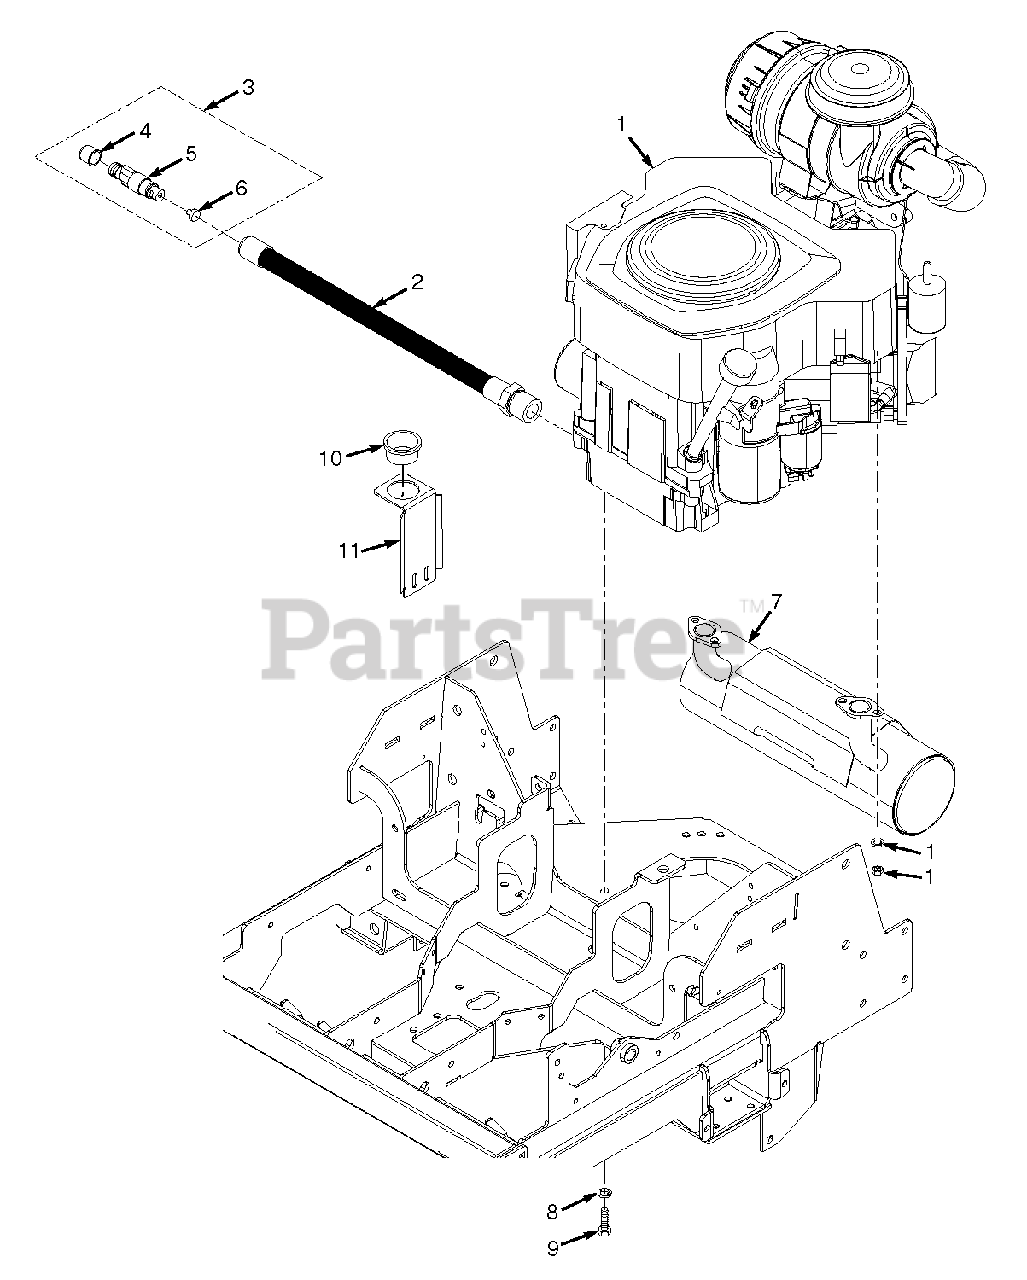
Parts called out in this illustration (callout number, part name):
1	Engine, Kawasaki FX691V
1	Engine, Kohler CV730
1	Engine, Kawasaki FX730V
1	Engine, Kohler CV740
1	Engine, Briggs & Stratton 44L977
2	Hose Assembly, Engine Oil Drain - Kawasaki FS/FX
2	Hose, Oil Drain - Briggs & Stratton ELS
2	Hose, Oil Drain - Kohler CV
3	Valve Assembly, Oil Drain
5	O-Ring
7	Muffler, Kawasaki FS/FX
7	Muffler, Briggs & Stratton
7	Muffler, Kohler CV
8	Lockwasher, 3/8" Spring (Kawasaki)
9	Bolt, Hex Head 3/8-16 x 1-1/4" (Kawasaki)
9	Bolt, Hex Head 3/8-16 x 1-1/4" Self Tap (Briggs and Kohler)
9	Bolt, Hex Head 5/16-18 x 1-1/2" (Right Front Engine Mounting, Briggs and Kohler Only)
9	Nut, Serrated Flange 5/16-18 (Right Front Engine Mounting, Briggs and Kohler Only)
10	Bushing, Thick Panel Snap
11	Bracket, Oil Drain Hose
